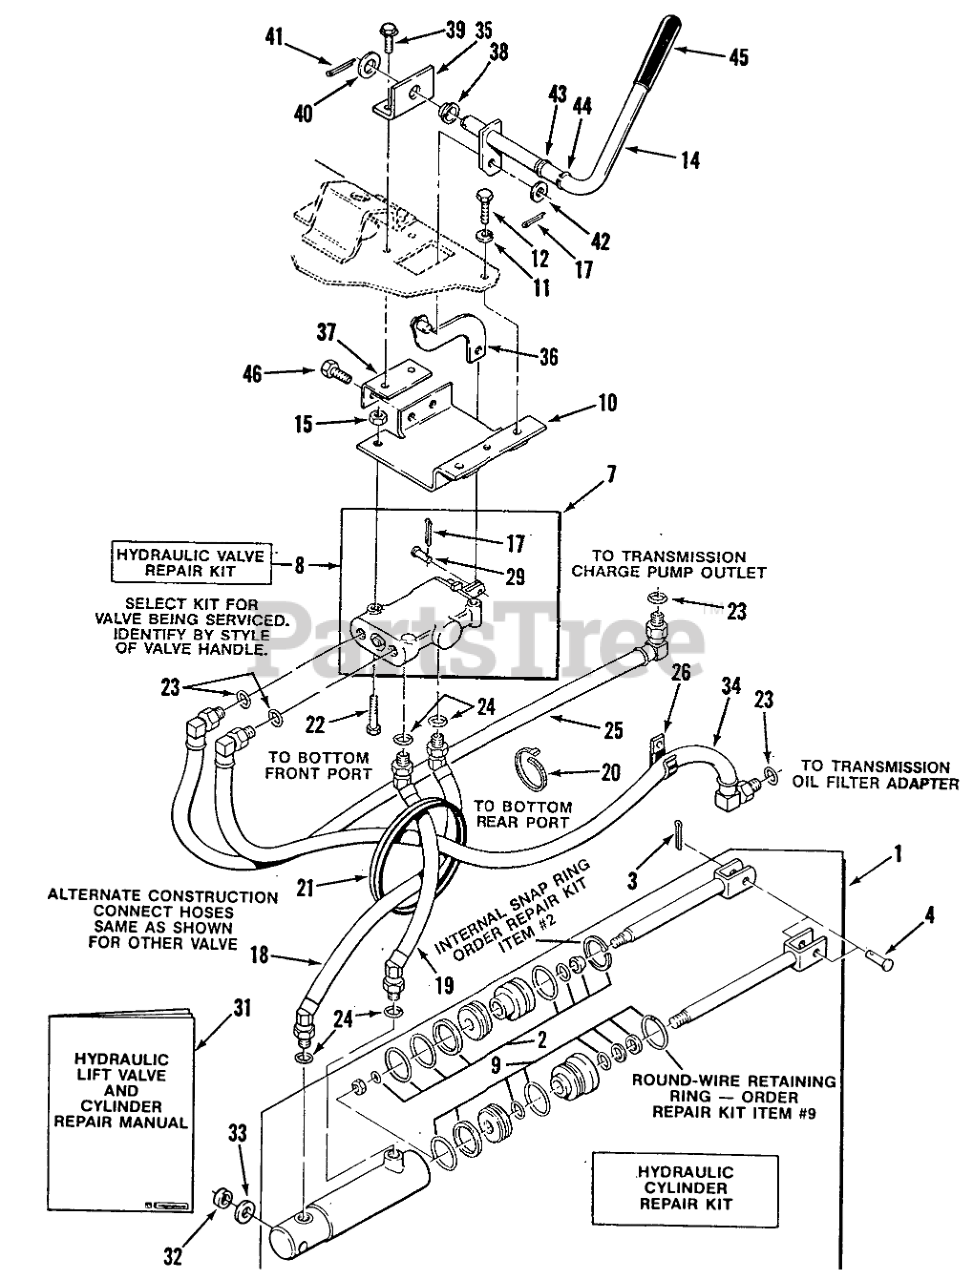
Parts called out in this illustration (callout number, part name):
1	CYLINDER
2	S/A O-RING&GASKET AS
4	CLEVIS PIN
7	ASS'Y-VALVE
8	S/A 110068 VALVE
9	S/A 108872 HYD CYL
10	ASS'Y-VALVE SUPPO B
11	Lockwasher
12	Bolt
14	DECAL-STRG THROTTLE
15	Nut
16	C-HOOK
17	Cotter Pin
18	Hose ASM-Hydraulic
19	Hose ASM-Hydraulic
20	PLASTIC TIE
21	GROMMET
22	Bolt 1/4-20 x 2
23	0-Ring
24	O RING
25	ASSY HOSE HYDRAULIC
26	CLIP
29	Pin
31	Repair Manual
32	Spacer
33	WASHER
34	ASSY HYD HOSE
35	SUPPORT-LEVER ASS B
36	ASS'Y-BAR LIFT B
37	BRACKET-SUPPORT B
38	NYLINER BUSHING
39	Bolt
40	SHIM-WASHER
41	Pop Rivet
43	BUSHING-NYLINER
44	Grip Ring
45	GRIP
46	Bolt
